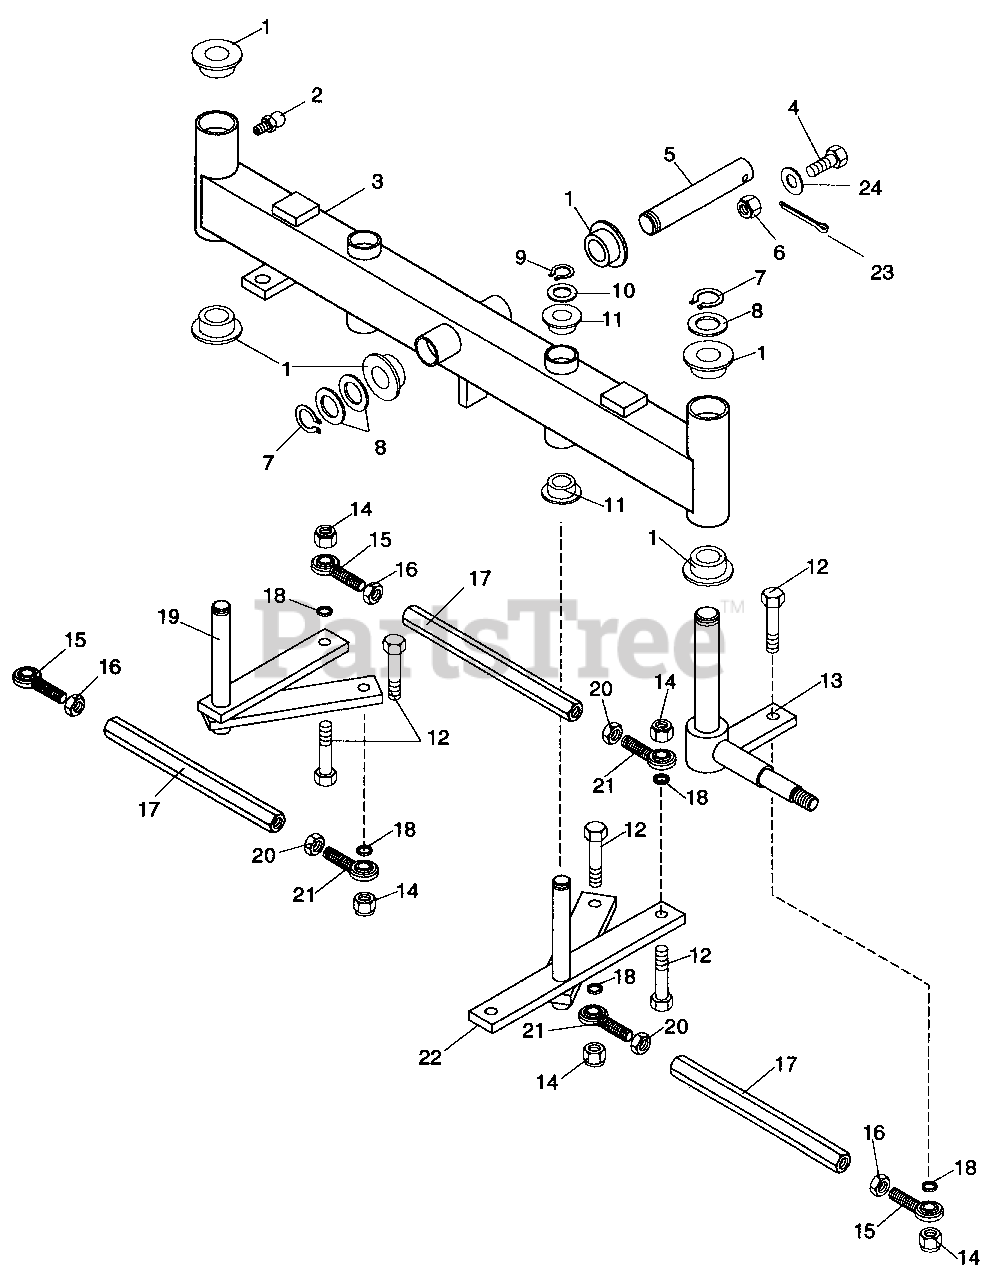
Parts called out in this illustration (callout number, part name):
1	BSHG-FLG 1.020 X 1.385 X .75 X 1.75 NY
2	FTG, LUBE; .25-28 SELF THREAD
3	WLDMT, AXLE
4	BLT-HEX .38-16 X 1.00 PL GR 5
5	SHAFT, PIVOT
6	NUT-LK-NYL .375-16 PL
7	RG-RTNG-EXT .906 X .078
8	BRG-NEEDLE .688 X .876 X .63
9	RG-RTNG-EXT .689 X .077
10	BRG-N-THRST .752 X 1.24 X .031
11	BSHG-FLG .762 X 1.0 X .580 X 1.48 NY
12	BLT-HEX .50-13 X 2.00 PL GR 5
13	WLDMT, KINGPIN L.H.
13	WLDMT, KINGPIN R.H.
14	NUT-LK-NYL .50-13 PL
15	ASM, ROD END(R.H.)
16	NUT-JAM .50-20 PL
17	ROD TIE
18	BUSH., S .520 X .625 X .125 ST
19	WLDMT, STEERING IDLER
20	NUT-JAM .50-20 LH THD PL
21	ASM, ROD END L.H.
22	WLDMT, STEERING ARM
23	PIN-COTR .250 X 2.00
24	WSHR-FL-STL .281 X .62 X .065 PL
